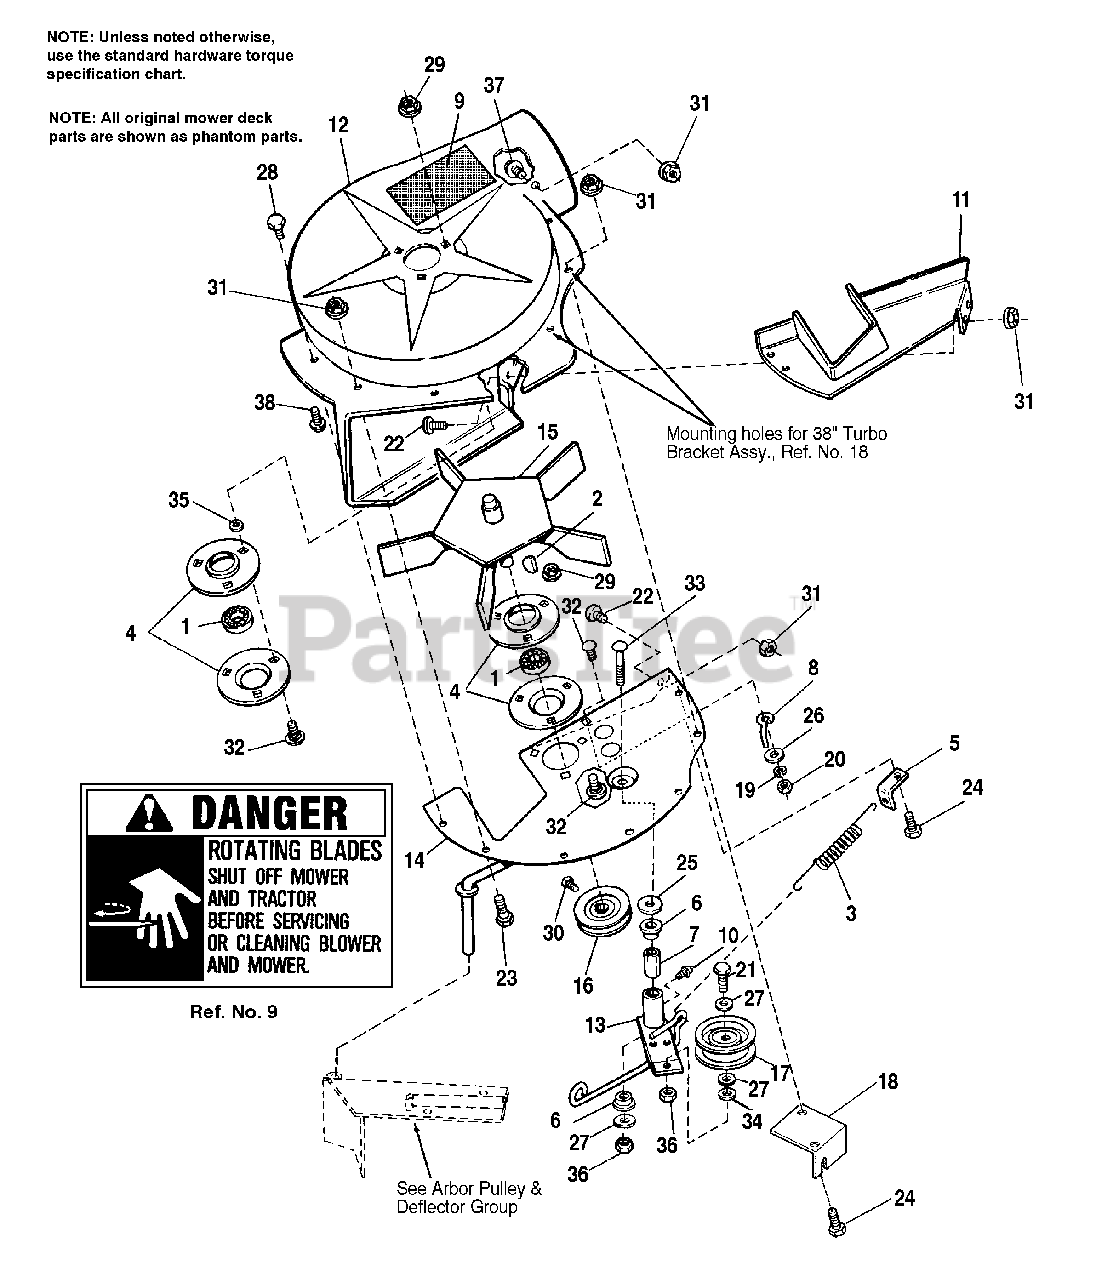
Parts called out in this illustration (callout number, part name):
2	KEY, Woodruff, Modified
3	SPRING, Tension
4	BEARING, Retainer
5	BRACKET, Anchor, Spring
9	DECAL, Danger, Blower
10	FITTING, Grease
11	PLATE, Cover
12	FAN HOUSING
13	LEVER ASSY, Turbo
14	PLATE ASSY.
15	FAN ASSY., 5 Blade
16	PULLEY, Driven
17	IDLER PULLEY ASSY.
18	BRACKET ASSY., Turbo
19	WASHER, Spring Lock, 5/16
20	NUT, Hex, 5/16
21	CAPSCREW, Hex Hd., 3/8-16 x 1-1/4
22	SCREW, Truss Hd., 1/4-18 x 5/8
23	CAPSCREW, Hex, 1/4-20 x 5/8
24	CAPSCREW, Hex Hd., 1/4-20 x 3/4
25	WASHER, Flat
26	WASHER, Flat
27	WASHER, Plain
28	CAPSCREW, Hex, Taptite, 1/4-20 x 1/2
29	NUT, Flange, Whizlock, 5/16-18
30	SETSCREW, Hex, Socket Hd., 5/16-18 x 5/16
31	NUT, Hex, Flange Lock, 1/4-20
32	CARRIAGE BOLT, 5/16-18 x 3/4
33	CARRIAGE BOLT, 3/8-16 x 2-1/4
34	WASHER, Flat
35	PUSH NUT, 3/8
36	NUT, Hex, Jam, Center Lock, 3/8-16
37	CARRIAGE BOLT, 1/4-20 x 5/8
38	SCREW, Wsh. Hd.., 1/4-18 x 5/8
